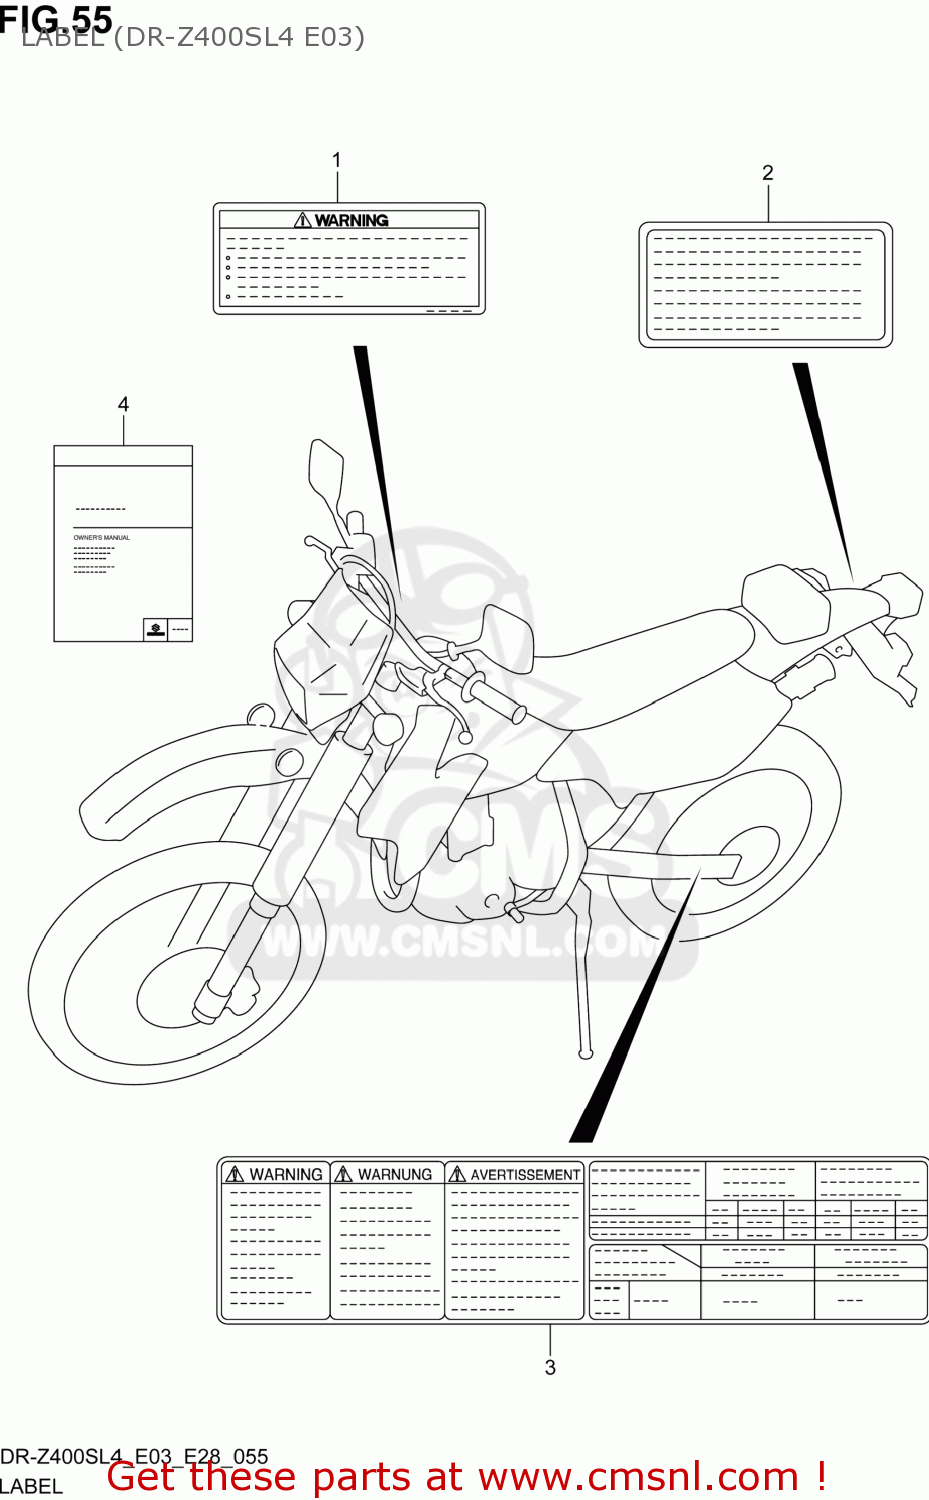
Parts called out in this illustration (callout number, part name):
1	LABEL,GENERAL WARNING
2	LABEL,MANUAL NOTICE
3	LABEL,TIRE INFORMATION
4	MANUAL,OWNER'S
